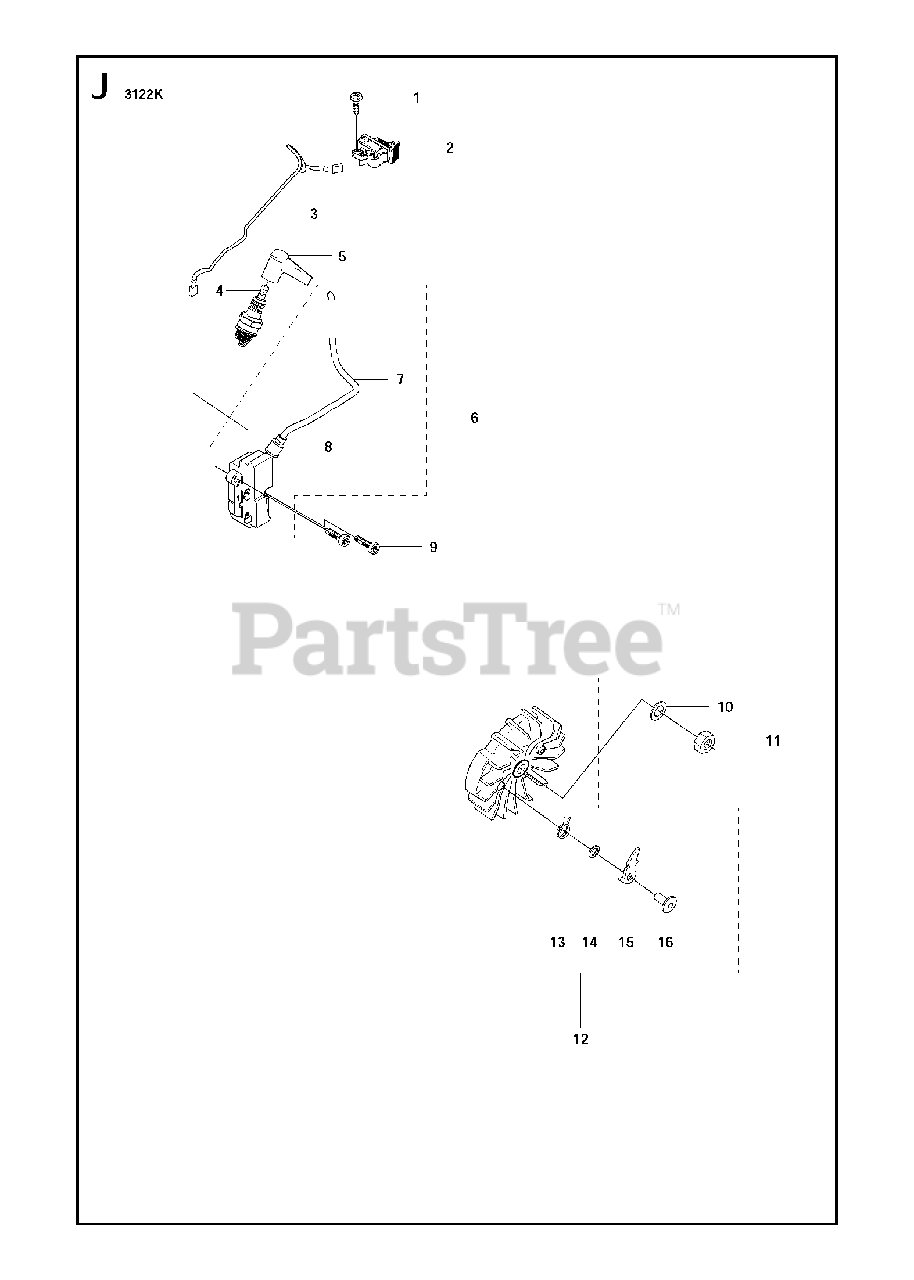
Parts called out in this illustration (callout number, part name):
1	SCREW CCRPANT
2	STOP SWITCH
5	SPARK PLUG CAP
6	IGNITION MODULEIncl. 7 - 8
7	IGNITION CABLE
9	SCREW ITXSCM
10	SPRING WASHER
12	FLYWHEEL ASSYIncl. 13 - 16
16	SCREW
